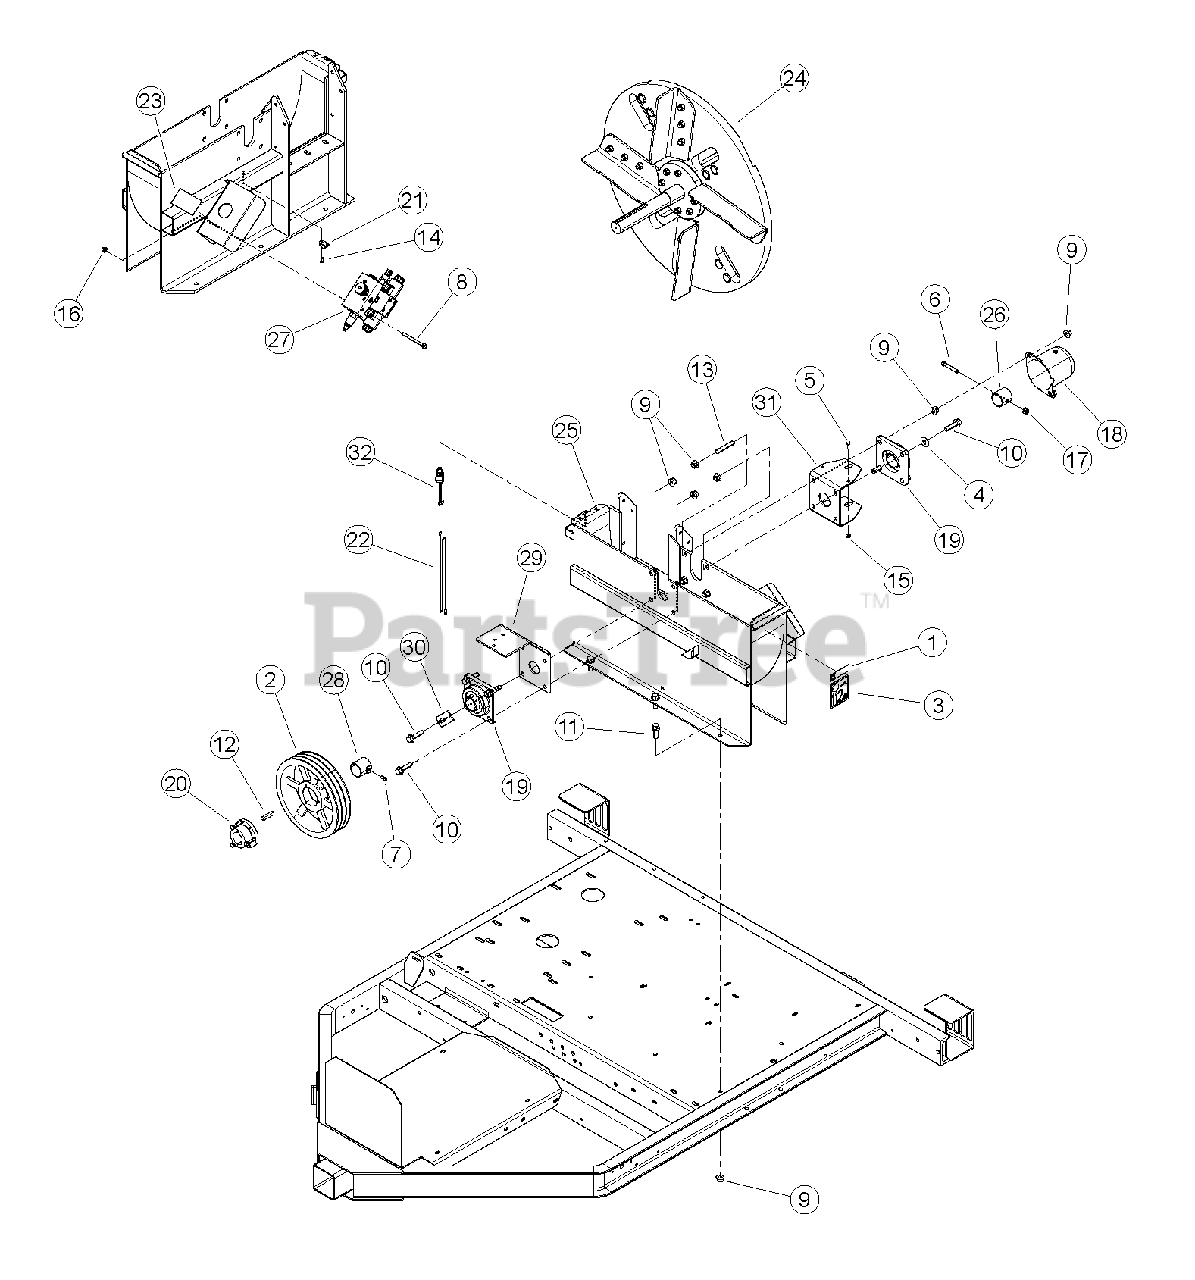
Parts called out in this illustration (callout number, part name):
1	DECAL, 72928S INFORMATION (CE COMPLIANT ONLY)
2	SHEAVE, 3BQ11.0 SK
3	DECAL, 112 DB (CE COMPLIANT ONLY)
4	WASHER, 1/2" FLAT ZP
5	BOLT, 1/4-20 X 3/4 HWH GR5 CZP
6	BOLT, 3/8 X 2-1/2 GR5 HHCS ZP
7	SCREW, 5/16-18 X 5/8 SQ HD SET
8	BOLT, 5/16 X 4 SERRATED FLANGE NC
9	NUT, 1/2-13 NYLOCK FLANGE
10	BOLT, 1/2-13 X 2 HWH GR5 CZP
11	BOLT, 1/2-13 X 1-1/2 GR5 FLANGE NC
12	KEY, 3/8" SQ X 2" LG PLAIN
13	STUD, 1/2"-13 X 3" LG B7 ZP
14	RIVET, AL BLIND 1/4 X 3/4 DOME HEAD
15	NUT, 1/4-20 NYLOCK-FLANGE
16	NUT, 5/16-18 NYLOCK-FLANGE
17	NUT, 3/8-16 NYLOCK FLANGE
18	CAP, LARGE SHAFT
19	BEARING, 1-3/4 4 BOLT FLANGE
20	BUSHING, SK 1-3/4"
21	CLAMP, CABLE MOUNT
22	DECAL, FEED SPEED
23	WIRE ASSEMBLY, 37" FM SPADE AND RING
24	ASSEMBLY, 9" CHIPPER ROTOR
25	WELDMENT, CHIPPER BOTTOM
26	COLLAR, CHIPPER LOCK
27	ASSEMBLY, HYDRAULIC FEED FLOW VALVE W/ PS
28	WELDMENT, SPACER
29	WELDMENT, GUARD SUPPORT
30	BRACKET, SENSOR SHORT MOUNT
31	BRACKET, ROTOR LOCK
32	ASSEMBLY, SEALED SWITCH
